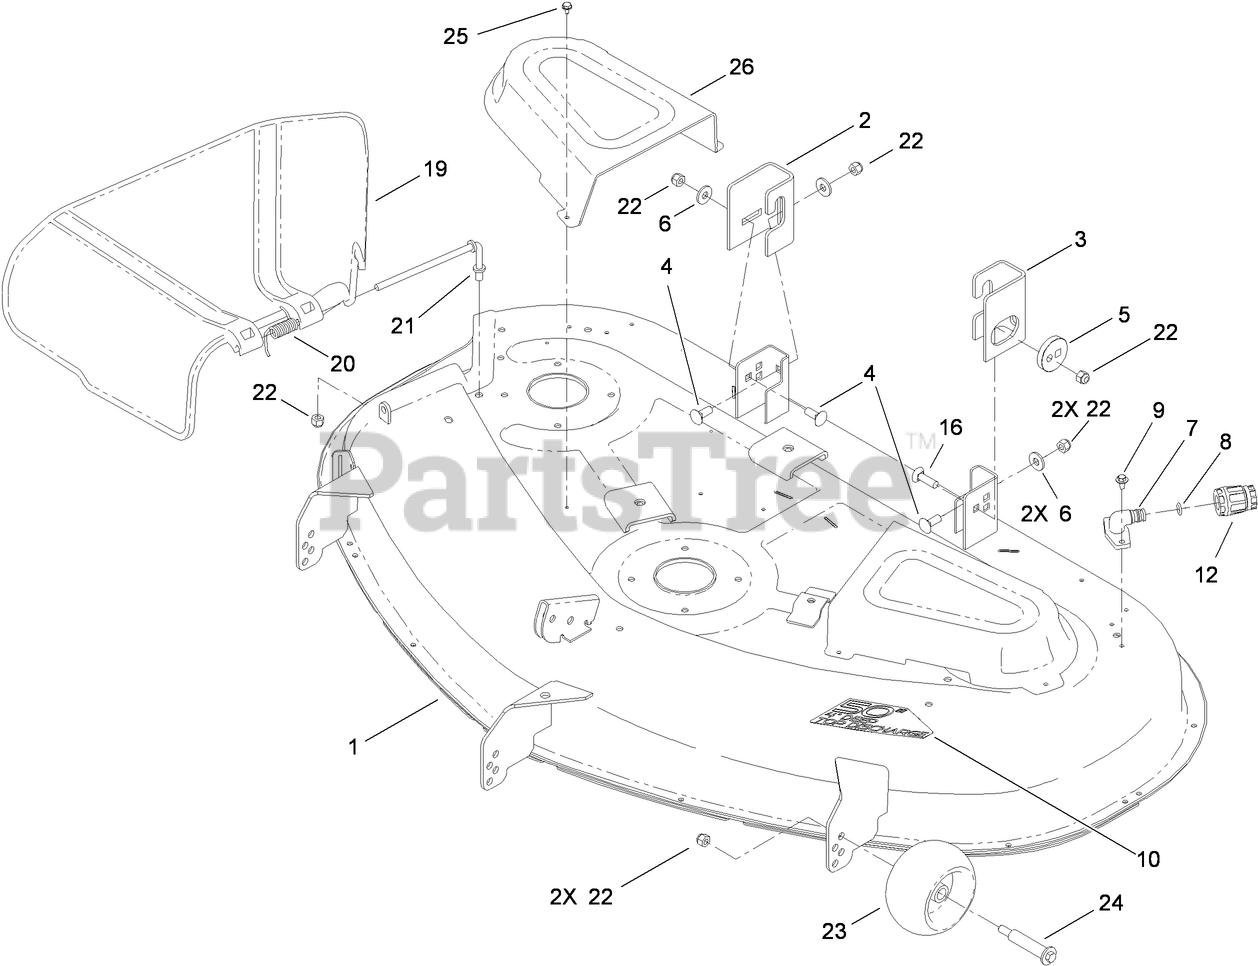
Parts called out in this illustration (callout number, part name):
2	BRACKET-HANGER, RIGHT REAR
3	BRACKET-HANGER, LEFT REAR
4	BOLT-CARR
5	ECCENTRIC
6	WASHER-HARDENED
8	O-RING
9	SCREW-HHFTF
12	CONNECTOR-HOSE
16	SCREW-CARR
19	DEFLECTOR
20	SPRING-TORSION
21	ROD-PIVOT
22	NUT-LOCK, NI
23	ROLLER-SCALP, ANTI
24	BOLT-SHOULDER
25	SCREW-HWHTF
26	COVER-BELT
